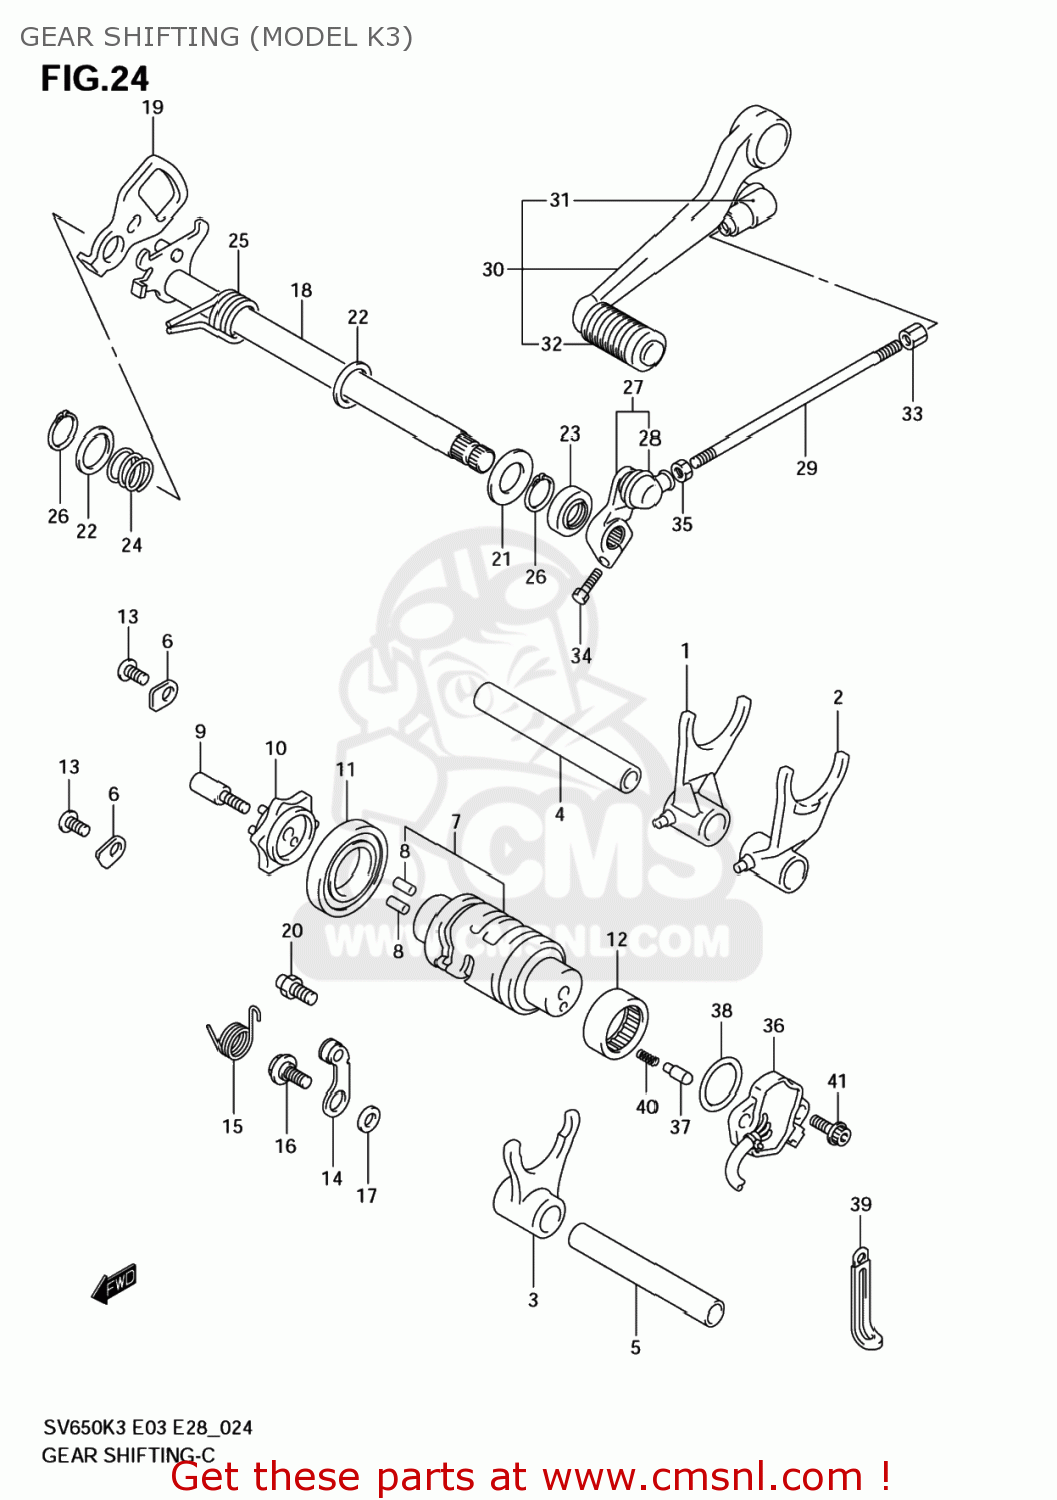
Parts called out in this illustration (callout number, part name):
1	FORK,GEAR SHIFT NO.1
2	FORK,GEAR SHIFT NO.2
3	FORK,GEAR SHIFT NO.3
4	SHAFT,GEAR SHIFT FORK
5	SHAFT,GEAR SHIFT FORK NO.1
6	RETAINER
7	CAM,GEAR SHIFT
8	PIN
9	BOLT,GEAR SHIF
10	PLATE,GEAR SHIFT CAM
11	BEARING(25X47X8)
12	BEARING(25X32X12)
13	SCREW
14	STOPPER,GEAR SHIFT CAM
15	SPRING,GEAR SHIFT CAM STOPPER
16	BOLT(6X14.3)
17	WASHER
18	SHAFT,GEAR SHIFT
19	PLATE,GEAR SHIFT CAM DRIVE
20	STOPPER,GEAR SHIFT ARM
21	WASHER(14X29X0.8)
22	SHIM(14X22X1)
23	SEAL,OIL(14X22X6)
24	SPRING
25	SPRING
26	CIRCLIP
27	ARM,GEAR SHIFT LINK
28	COVER,DUST
29	ROD,GEAR SHAFT LINK
30	LEVER ASSY,GEAR SHIFT
31	COVER,DUST
32	RUBBER,GEAR SHIFT PEDAL
33	NUT
34	BOLT
35	NUT
36	BASE ASSY,GEAR SHIFT TERMINAL
37	PIN(5X15.5)
38	O RING(D:2.4,ID:25.7)
39	CLAMP(L:65 T:0.8)
40	SPRING
41	BOLT
